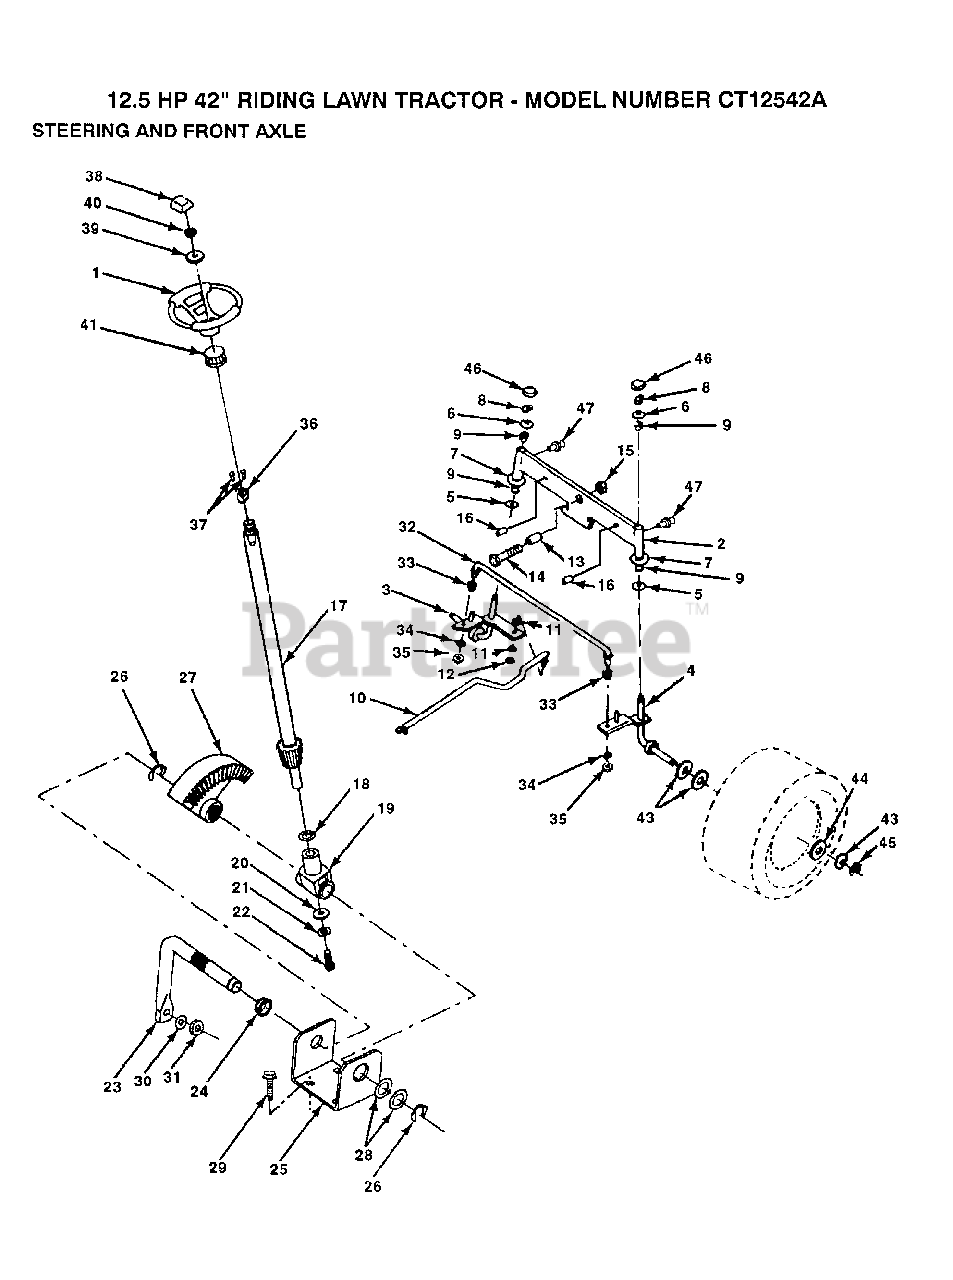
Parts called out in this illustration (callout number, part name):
4	SPINDLE ASM RH
5	WASHER .T
6	WASHER
7	WASHER
8	RING
9	COL. SRTG. BEAR.
11	LOCKWASHER
13	BEARING
14	BOLT HEX 5/8-11
16	AXLE PIN
17	SHAFT ASM
18	THRUST WASHER
19	SUPPORT.SHAFT
21	LOCKWASHER
22	"SCREW,SPECIAL"
24	NYLINER T
25	"BRKT,STEERING"
26	RING
28	WASHER .T
29	SCREW
30	LOCKWASHER
32	TIE ROD
33	WASHER M
34	LOCKWASHER
35	NUT.LOCK.5/16-24
38	INSERT-WHEEL LT
39	WASHER T
40	GRIPCO NUT
41	ADAPTER-WHEEL LT
43	WASHER
44	WASHER
45	RING
46	CAP
47	ZERK M
